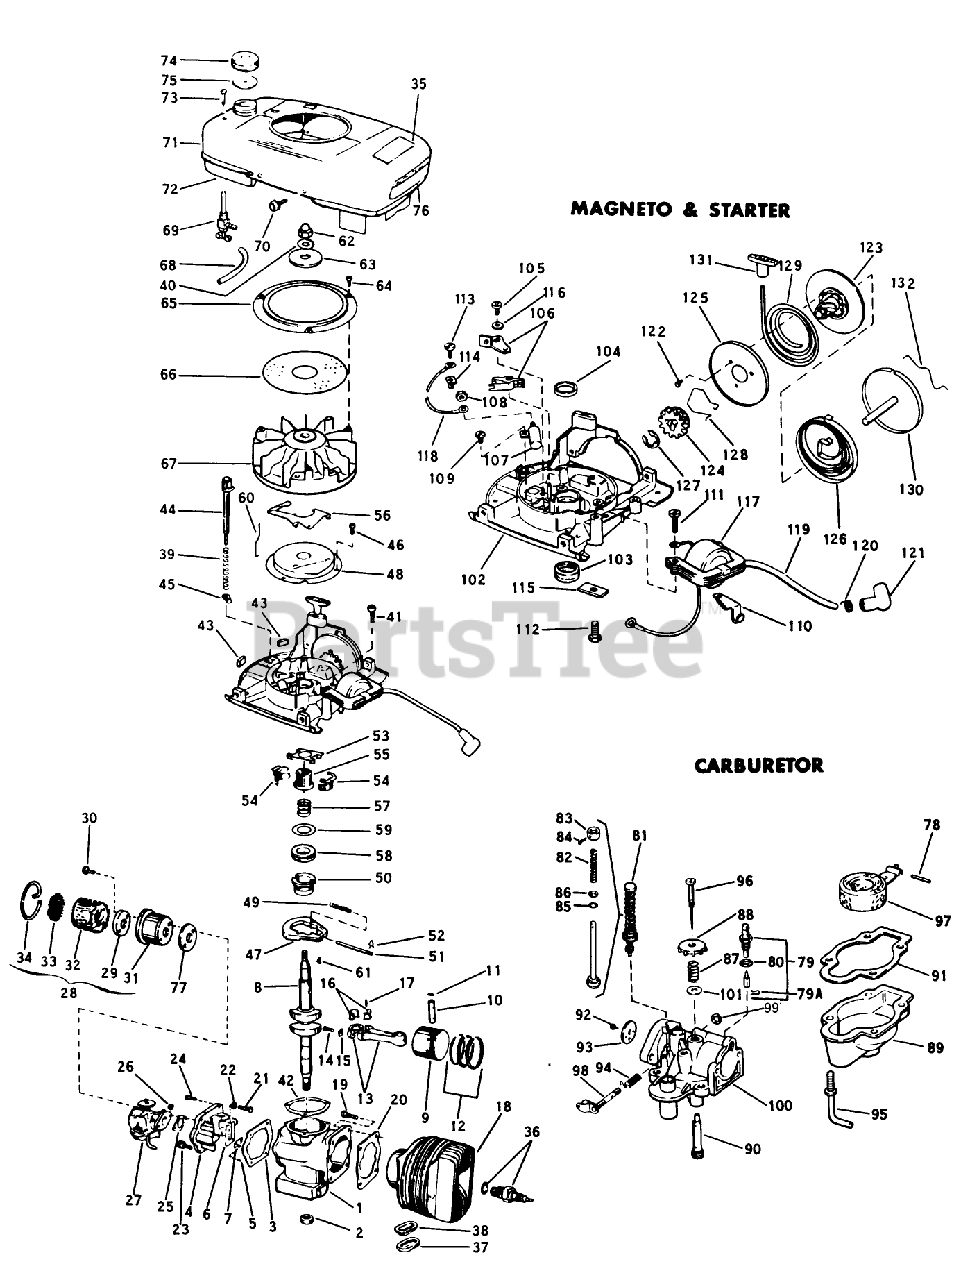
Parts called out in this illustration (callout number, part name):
7	PLATE-BACKUP, REED
11	RING-RETAINING
16	LINER ASM
20	GASKET S
23	SCREW S
24	SCREW S
25	GASKET S
26	STOP NUT
29	BACK-UP PLATE
30	SCREW S
32	ELEMENT
36	Spark Plug
37	GASKET S
39	SPRING S
42	GASKET S
46	SCREW S
47	FLYWEIGHT S
48	DUST COVER S
49	SPARK ADV. SPRING S
50	SPARK ADV. S
51	PIN,SPARK ADV. S
52	SPARK ADJ. SPRING
55	COLLAR S
56	LEVER-GOVERNOR S
58	THRUST COLLAR S
65	Ring-Flywhl. Scrn.
69	VALVE&SCREEN SM
70	SCREW S
81	PRIMER AY S
82	Spring-Compression
87	Spring-Ndl. Adj.
91	GASKET S
92	Screw-Throttle Shaft Disc
93	THROTTLE DISC S
96	NEEDLE AY. S
98	THROTTLE LEVER S
99	RING GRIP S
103	BRG. & SEAL AY.
106	BREAKER AY. S
112	SCREW S
114	NUT - CLIP
119	LEAD AY. S
121	Cover-Rubber
124	STARTER PINION S
126	SPRING S
128	STARTER SPRING S
132	SPRING S
